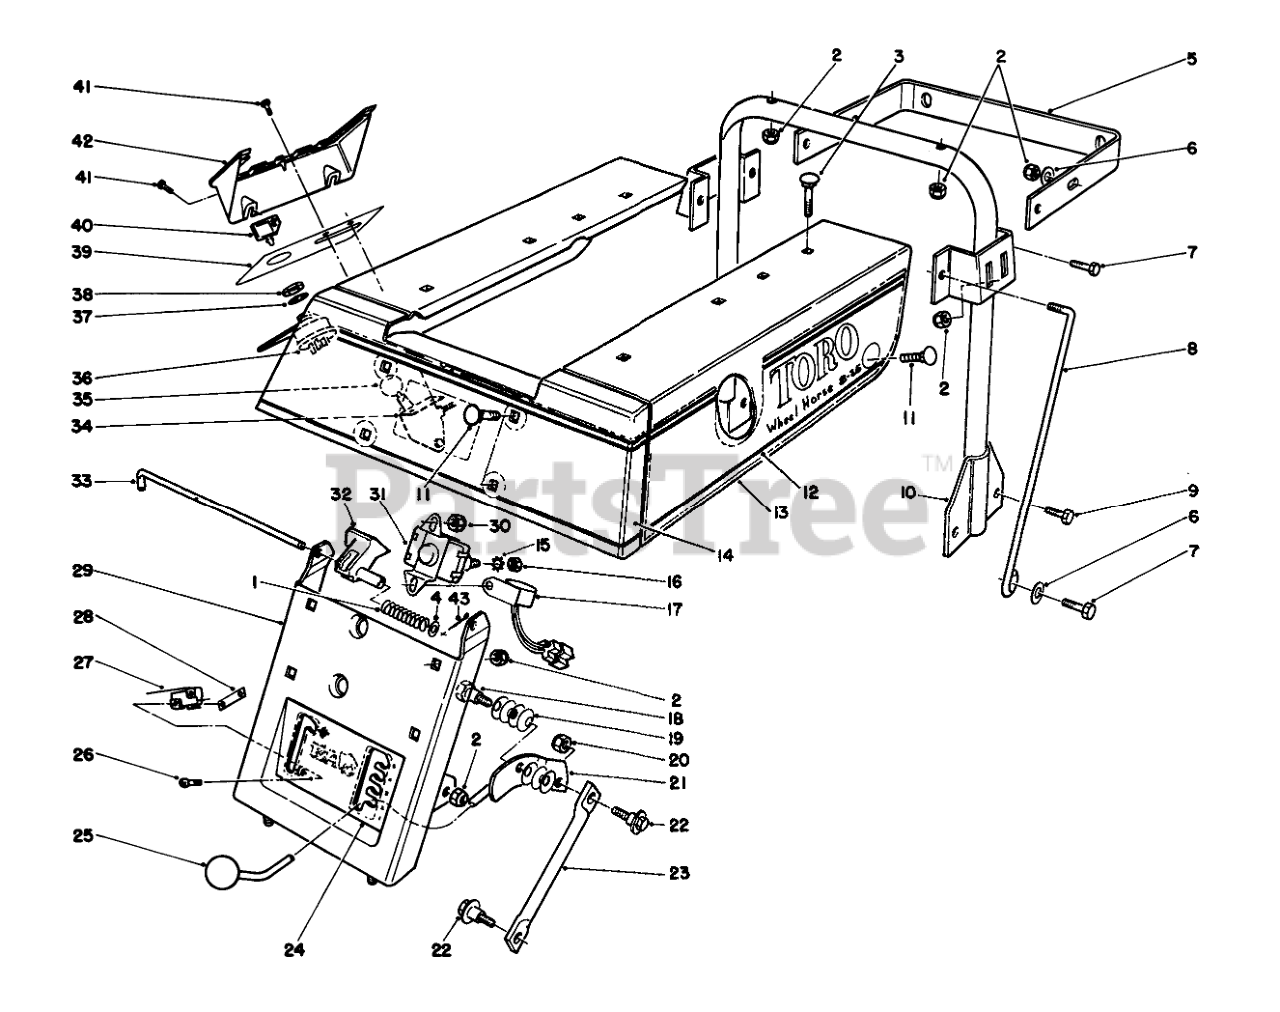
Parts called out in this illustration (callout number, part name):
1	SPRING-COMPRESSION
2	NUT-LOCK, NI
3	SCREW-CARR
4	WASHER-FLAT
5	Standbar
6	WASHER-PLAIN
7	SCREW-HH
8	BRACE-SEAT SUPPORT
9	SCREW-HH
10	Seat Support W.A.
11	SCREW-CARR
12	DECAL - LH 825 TORO
13	Body W.A.-Rear
14	DECAL - FRONT TORO
15	WASHER-LOCK/EXT
16	NUT-JAM
17	Module Interlock
18	BOLT-SHOULDER
19	WASHER-BELLEVILLE
20	NUT-LOCK, NI
21	HOC HDLE WA
22	BOLT-SHOULDER
23	LINK-HOC
24	DECAL - HOC
25	KNOB-CONTROL
26	SCREW-SPH
27	SWITCH-MICRO
28	NUT-SPEED
29	Support W.A.-Seat
30	NUT-LOCK, NI
31	SOLENOID
32	PROP-SEAT
33	ROD-SEAT BASE
34	CONTROL-THROTTLE
35	Knob
36	Switch-Ignition (Incl. Ref. #37 & 38)
37	WASHER-TOOTH, INTERNAL
38	NUT-HH
39	DECAL - CONTROL PANEL
40	KEY-IGNITION
41	SCREW-THD FORM, HWH
42	COVER-CONTROL PLATE
43	SCREW-HSH
